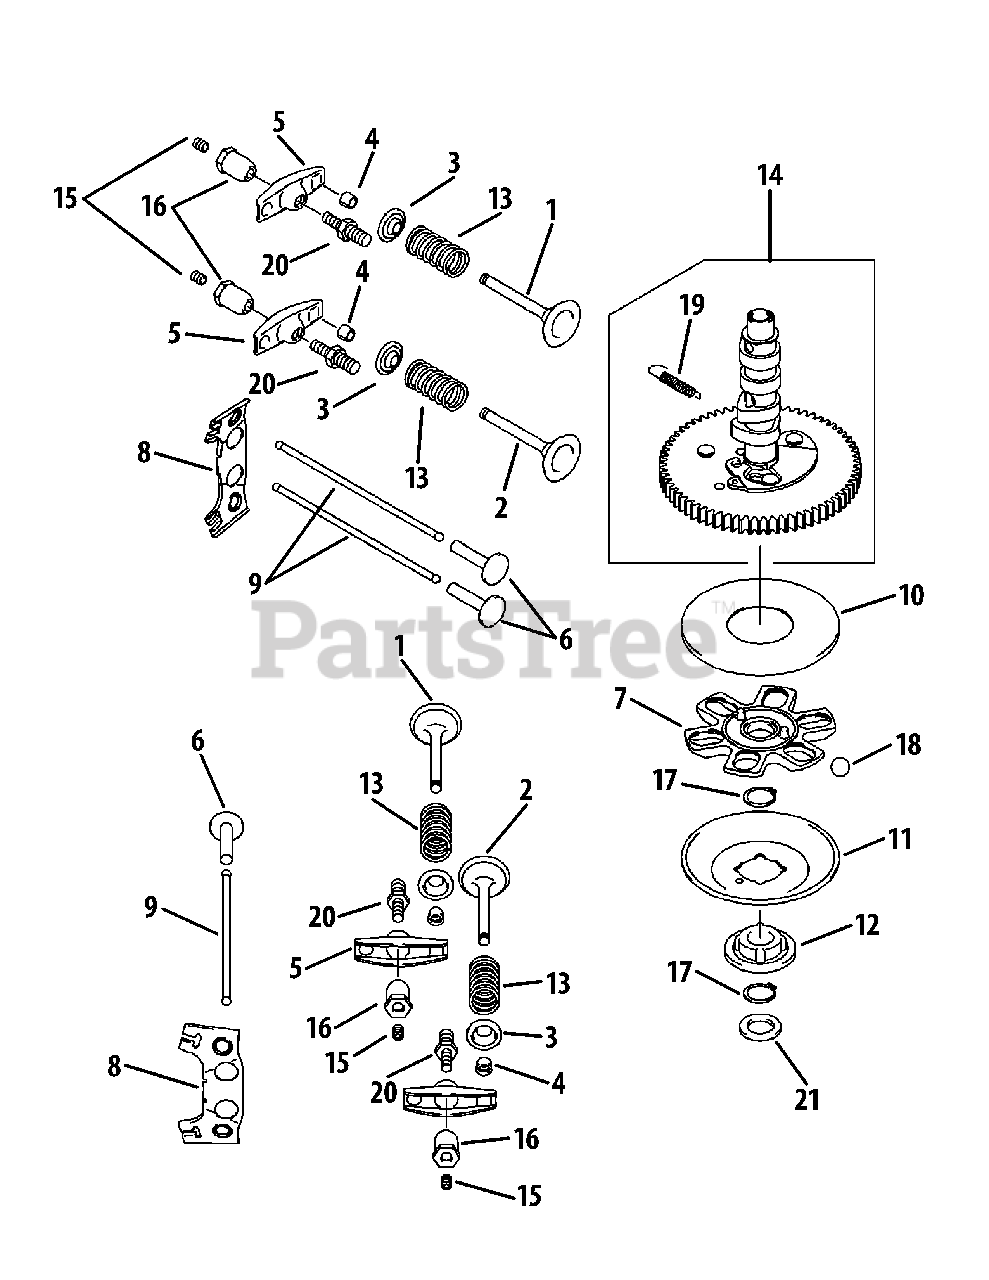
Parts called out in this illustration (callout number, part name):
2	Exhaust Valve
3	Valve Spring Retainer
11	Governor Plate
14	Complete Camshaft
17	Snap Ring
18	Ball
19	Spring
